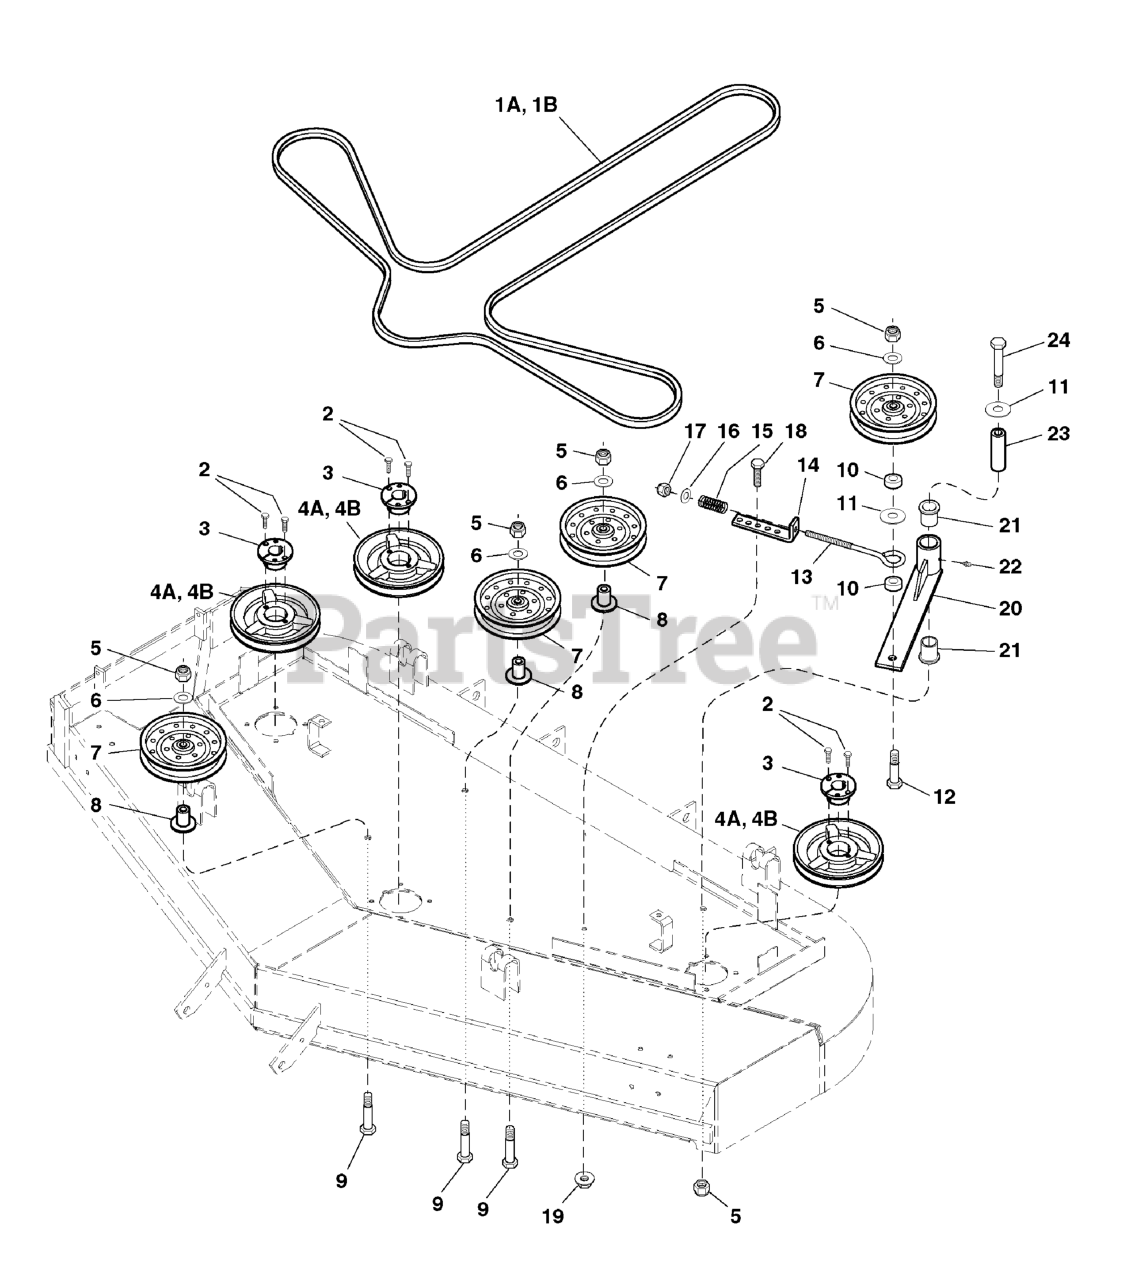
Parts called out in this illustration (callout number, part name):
1A	BELT
1B	BELT, 5V, 207.90"EL, LRG ARAMID, WRP, RC
2	BOLT, 1/4-20 X 1" GD5 CZ
3	BUSHING, Tapered Hub
4A	PULLEY, Spindle
4B	PULLEY, Spindle
5	NUT, 1/2-13 HEX NYLON LOCK
6	WASHER, 1/2 SAE
8	IDLER PULLEY MOUNT
9	BOLT, 1/2-13 X 3-1/2, HEX HD, GD5, CZ (SV)
10	SPACER, .52 x 1.00 x .44
11	WASHER, 1/2" USS
12	BOLT, 1/2-13 X 3" GD5 CZ
13	EYEBOLT, 3/8" x 8"
14	SPRING ANCHOR
15	SPRING, Compression
16	WASHER, 3/8 SAE
17	NUT, 3/8-16 HEX NYLON LOCK
18	BOLT, 3/8-16 X 1" GD5 CZ
19	NUT, 3/8-16 Hex Serrated Flange
20	IDLER ARM
21	BUSHING, FLANGE
22	GREASE FITTING
23	SPACER, .52 x 1.00 x 3.50
24	BOLT, 1/2-13 X 4" GD5 CZ
